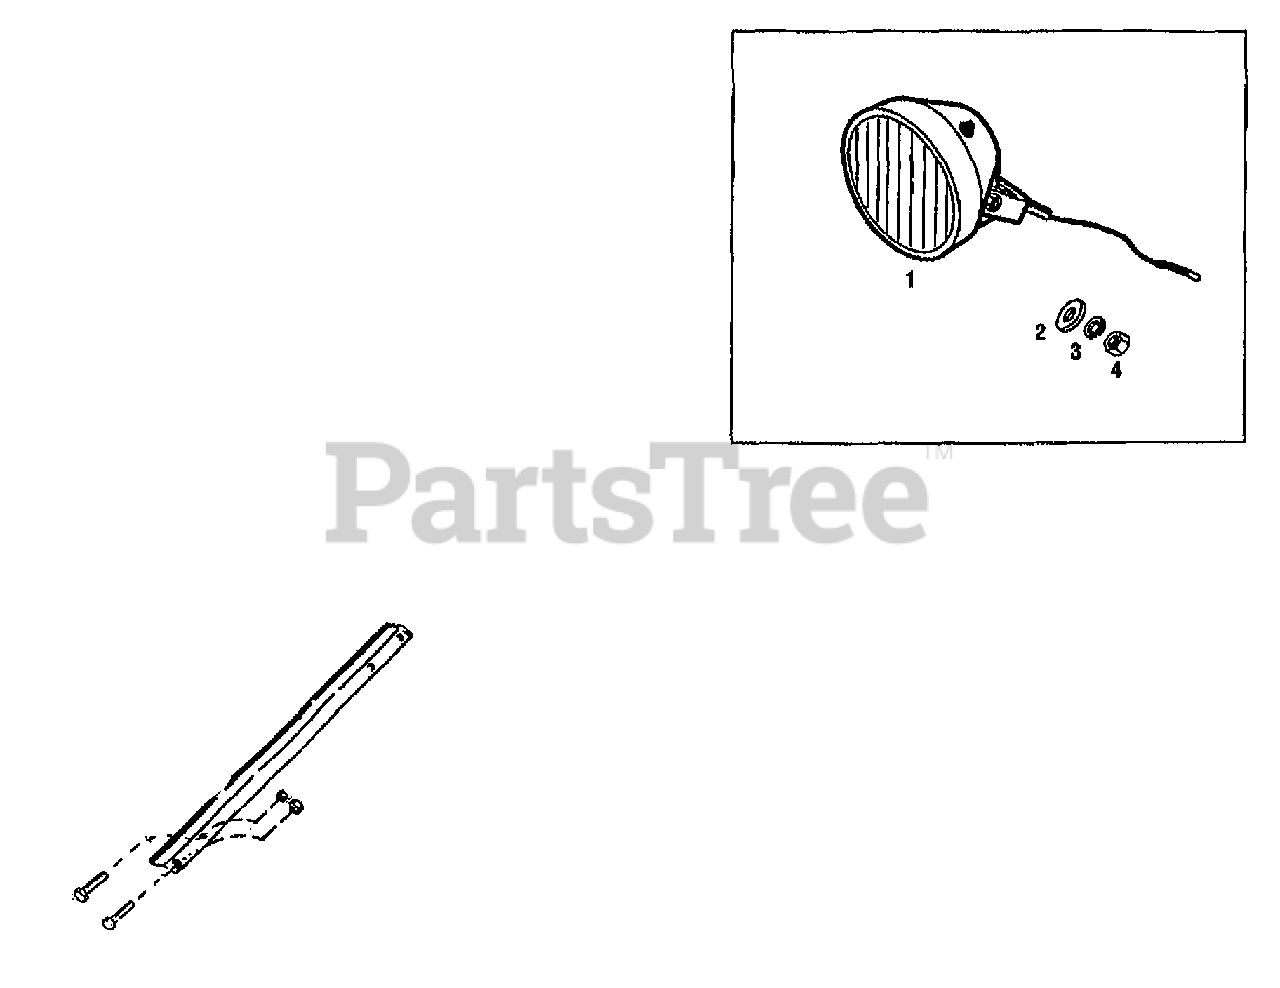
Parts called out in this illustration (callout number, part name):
1	ASSM-LIGHT
2	WASHER-FLAT 3/8 SAE
3	WASHER-LK .375 @ DEPL
4	NUT-HEX 3/8-16 ZP
